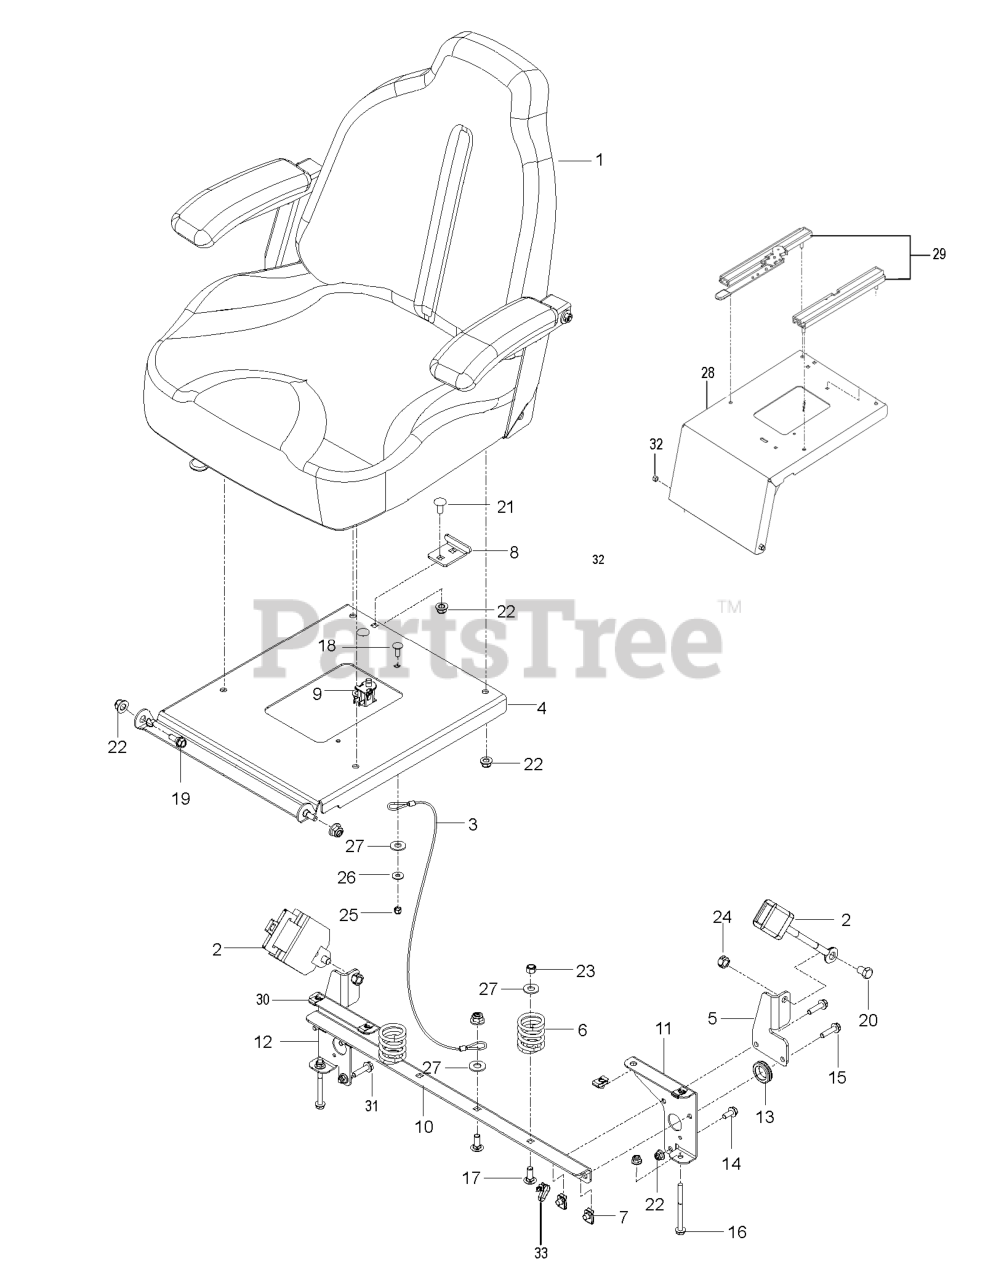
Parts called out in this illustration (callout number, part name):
1	SEAT.ASM.907.TRACK.W/O.BELT
2	SEAT BELT, RETRACTABLE
3	SEAT LANYARD
4	SUPPORT.SEAT.ORANGE
5	MOUNT, SEAT BELT, BLACK
5	MOUNT.SEAT.BELT.BLACK
6	SPRING.COMPRESSION.SEAT.BLACK
7	U-CLIP 5/16-18 NUT RETAINER
8	STOP, SEAT - BLACK
9	SEAT SWITCH
10	SUPPORT.SEAT. BLK
10	SUPPORT, SEAT
11	SUPPORT, RT, BLK
11	SUPPORT.RT.BLK
12	SUPPORT.LT.BLK
13	RUBBER GROMMET
14	HHFS 5/16-18 X 3/4
15	HHFS 5/16-18 X 1.25 TPBLT GD 5
16	BOLT.HEX.FLNG.5/16-18X3.75
16	HHFS 5/16-18 X 3 3/4
17	RHSNB 3/8C X 1
18	1/4-20X3/4 CARR BLT
18	RHSNB 1/4C X 3/4
19	SB 5/16-18 HEX HD GD5, BLK ZN
20	SCREW 7/16-20 X 1 HHB GR5
20	HCS 7/16-20 X .75 GD 5
21	RHSNB 5/16-18 X 3/4 GR5 BLK ZN
22	NUT.71038.31-18.HEX.NYLOCK
22	5/16-18 NYLOC FLANGE NUT
23	NUT 3/8-16 NYLOC
24	NUT HEX 7/16F LOCK RP
25	NUT.1/4-20.HEX.NYLOC.ZD
26	WASHER PM
26	WASHER 1/4 FLAT
27	RP WASHER 3/8 FLAT
28	KIT.SEAT.MOUNT.W/DECAL
29	4"SINGLE LOCK TRACK SET W/HDWR
30	SUPPORT, LT, BLK
31	HHFS 5/16-18 X 3/4
32	NUT 5/16 NYLOC
33	TIE WRAP, 8-3/8", W/CLIP
